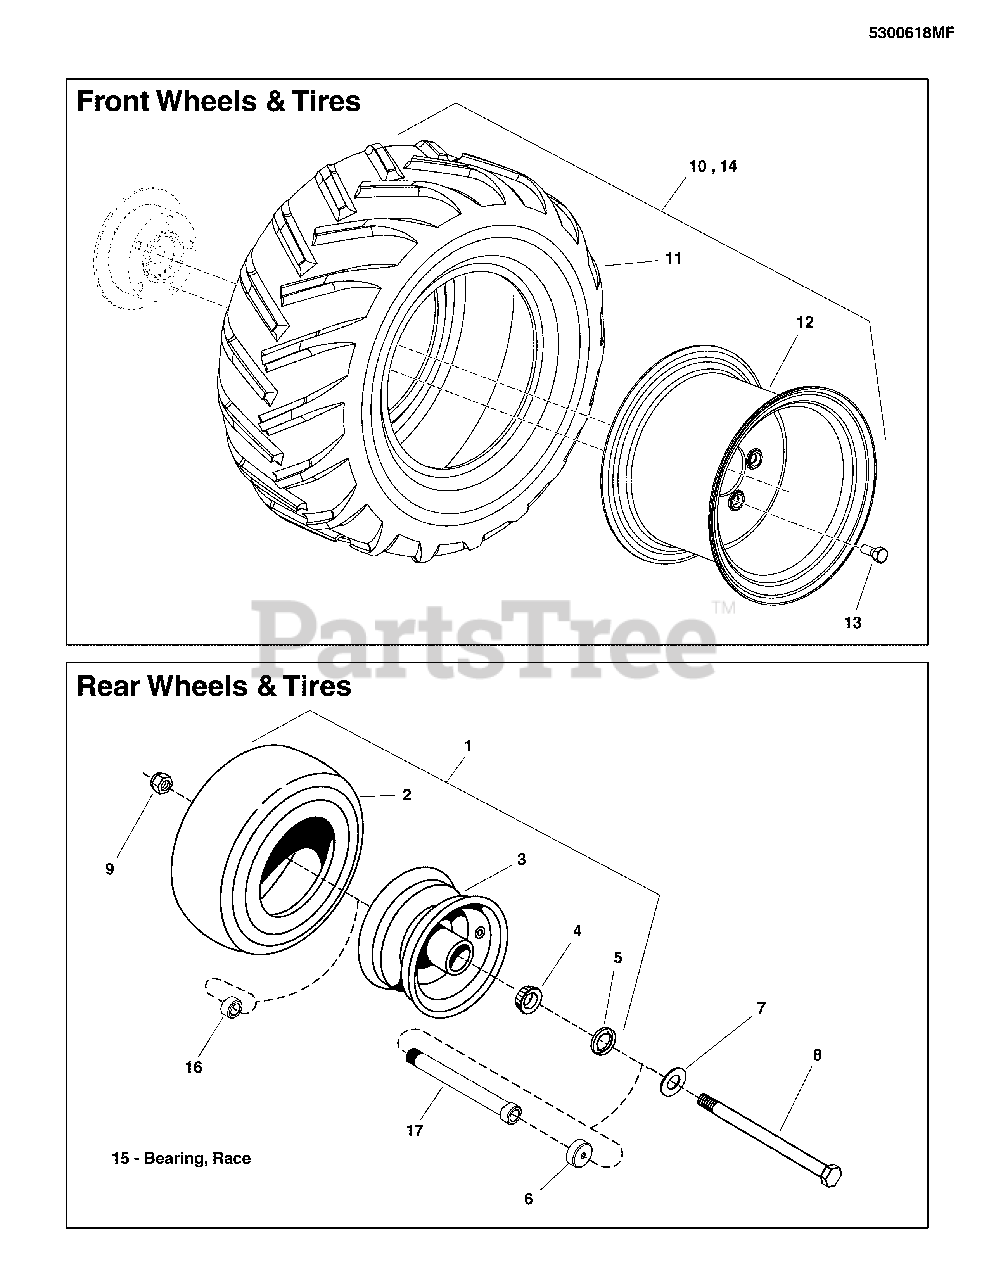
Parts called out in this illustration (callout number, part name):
1	TIRE ASSY, 13 X 6.5 SILVER
2	TIRE, FRONT
3	WHEEL ASSEMBLY
4	BEARING, TAPERED CONE
6	DEBRIS COVER, CASTER WHEELS
7	WASHER, 1/2 SAE
8	BOLT, 1/2-13 X 9 GD5 YZ
9	NUT, 1/2-13 HEX NYLOCK FLANGE
10	TIRE, ASSM, 24 X 12 X 12, CHEVRON, LH
11	TIRE, 24 X 12.00 - NHS, CHEVRON
12	WHEEL, 12 X 9.5, 5/4.5 BC, -1.81
13	BOLT, WHEEL LUG, 1/2 X 1-5/8
15	BEARING, RACE
16	NUT, BEARING ADJUSTER, AXLE
17	BEARING ADJUSTER, SPACER, 7.062LG
